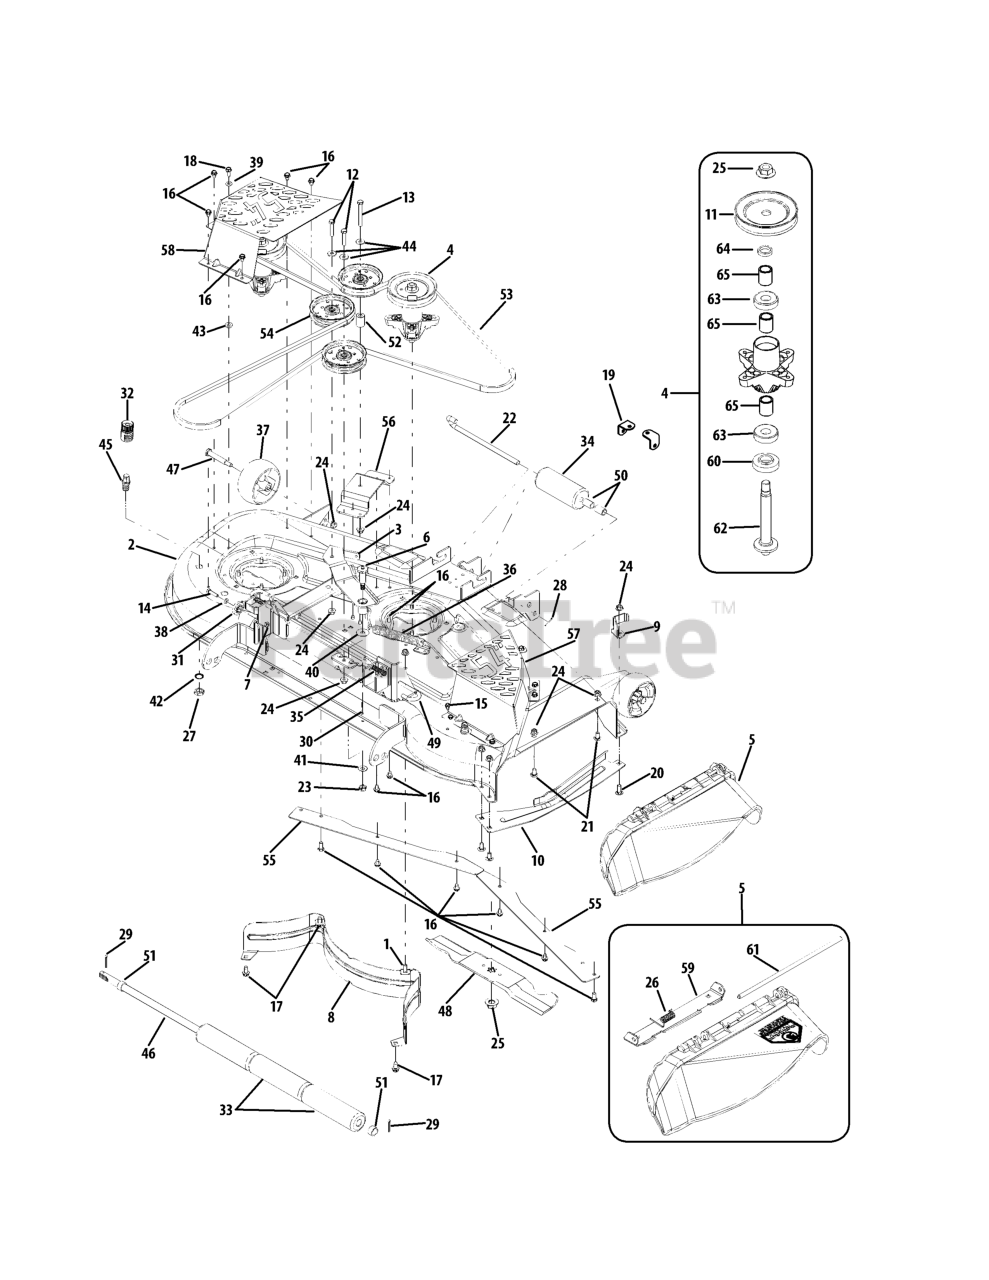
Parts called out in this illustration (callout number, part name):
1	Carriage Screw, 3/8-16 x 1.00
2	Deck Housing
3	Idler Assembly
4	Spindle Assembly
5	Discharge Chute Assembly
6	Shoulder Bolt Assembly
7	Deck Hanger Bracket
8	Rear Inner Baffle
9	Stop Bracket
10	Finger Guard
11	V-Type Pulley, 5.39
12	Hex Cap Screw, 3/8-16 x 1.75
13	Hex Cap Screw, 3/8-16 x 3.0
14	Hex Cap Screw, 5/16-18 x 1.25
15	Hex Washer Screw, 1/4-20 x .5
16	Hex Washer Screw, 5/16-18 x .750
17	Hex Washer Screw, 3/8-16 x .75
18	Hex Washer Screw, 5/16-18 x .875
19	Frame Support Bracket
20	Hex Screw, 3/8-16 x 1.00
21	Carriage Screw, 3/8-16 x .75
22	Roller Pin, .5 x 10.06
23	Hex Lock Nut, 7/16-14
24	Hex Insert Flange Lock Nut, 3/8-16
25	Hex Flange Nut, 5/8-18
26	Torsion Spring, .44 ID x 2.00
27	Hex Nut, M16-1.5
28	Cotter Pin, 3/32 x 1.0
29	Cotter Pin, 5/32 x 1.25
30	Cotter Pin, 1/8 x 1.25
31	Deck Adjustment Gear
32	Water Nozzle Adapter
33	Deck Roller, 7.895
34	Front Roller
35	Compression Spring, .535 x 1.751
36	Extension Spring, .94 x .04609
37	Deck Ball Wheel, 5.0
38	Lock Washer, 5/16
39	Flat Washer, .344 x .688 x .065
40	Flat Washer, .442 x 1.39 x .06
41	Bell Washer, .45 x 1.0 x .062
42	Lock Washer
43	Flat Washer, .407 x .812 x .135
44	Flat Washer, .38 x .93 x .110
45	Deck Wash Nozzle
46	Shaft, .75 x 26.893
47	Shoulder Screw, .5 x 2.5 x 3/8-16
48	Blade, 18.5
49	Deck Hanger Rod
50	Spacer, .55 x .75 x 1.125
51	Spacer, .82 x 1.0 x.53
52	Spacer, .38 x .9 x 1.313
54	Idler Pulley, 4.25 Dia
55	Deck Skirt
56	Stationary Idler Bracket
57	Belt Cover, RH
58	Belt Cover, LH
59	Chute Mounting Bracket
60	Spacer, .79 x 1.82 x .55
61	Hinge Pin
62	Spindle Shaft, 6.95
63	Ball Bearing
64	Spacer, .79 x 1.25 x .175
65	Spacer, .80 x 1.10 x 1.32
